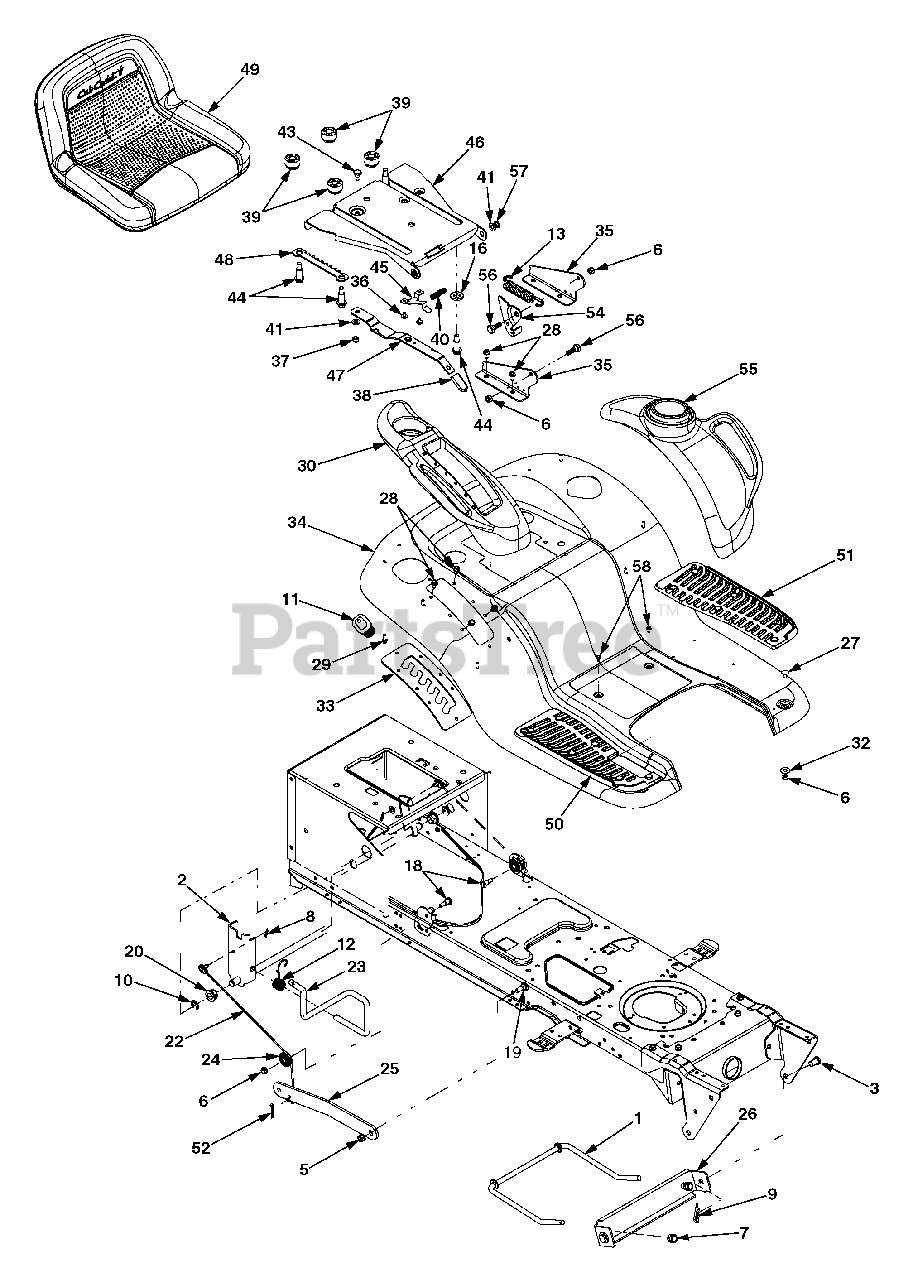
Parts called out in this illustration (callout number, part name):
1	Deck Stabilizer Rod
2	Lift Shaft Assembly
3	Clevis Pin, .5 x .78
5	Flange Lock Nut, 3/8-16
6	Lock Nut, 5/16-18
7	Hex Nut, 1/2-13
8	Internal Cotter Pin
9	Internal Cotter Pin
11	Handle Grip
12	Torsion Spring
13	Extension Spring, .84 x 4.6
16	Flat Washer, .31 x 1.062 x .134
18	Hex Cap Screw, 5/16-18 x .62
19	Shoulder Screw, 3/8-16
20	Hex Flange Bearing
22	Lift Cable, 16.16
23	Lift Handle
24	Roller Pulley
27	Carriage Bolt, 5/16 x .62
28	AB Screw, 5/16-12 x .75
29	Self-tapping Screw, 1/4-15 x .75
30	Fender Cover RH
32	Flat Washer, .349 x 1.0 x .063
36	Screw, #10-16 x .375
37	Hex Flange Lock Nut, 1/4-20
38	Seat Adjuster Grip
40	Compression Spring, .41 x 1.5
41	Spring Washer, .265 x .562 x .025
42	Flat Washer, .344 x .62 x .03
43	Shoulder Screw, .340 x .285,1/4-20
44	Shoulder Screw, .50 x .50, 3/8-16
45	Seat Stop
48	Seat Adjustment Selector
49	Medium Back Seat
50	RH Foot Pad
51	LH Foot Pad
51	Foot Pad Clips
52	Cotter Pin
54	Seat Lift Bracket
55	Fender Cover LH
56	Shoulder Screw, .437 x .268; 5/16-18
57	Speed Nut, .3125 ID
58	TT Screw 1/4-20 x 0.5
